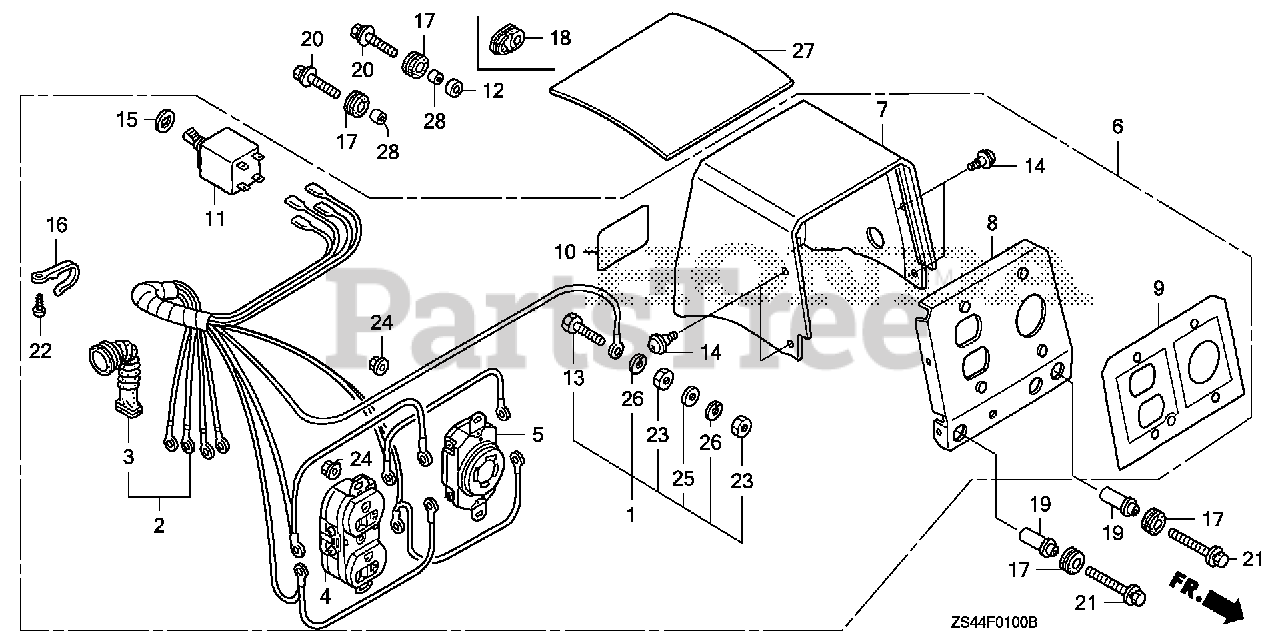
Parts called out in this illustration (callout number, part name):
1	TERMINAL SET, GROUND
2	WIRE HARNESS ASSY.
3	GROMMET, MAIN WIRE
4	RECEPTACLE (20A/125V) (EAGLE / RONG FENG)
5	RECEPTACLE (20A-125/250V)
6	BOX ASSY., CONTROL (NOT AVAILABLE)
7	COVER, CONTROL BOX
8	PANEL, FR.
9	MARK, PANEL SWITCH
10	MARK, PROTECTOR (ON-0FF)
11	PROTECTOR, CIRCUIT (13A)
12	COLLAR, CABLE CLAMP
13	BOLT, HEX. (6X22)
14	SCREW, SPECIAL (4X7.5)
15	WASHER, CROWN
16	TIE, CABLE
17	RUBBER, CONTROL BOX
19	COLLAR, CONTROL BOX
20	BOLT-WASHER (6X25)
21	BOLT-WASHER (6X45)
22	SCREW, TAPPING (4X16) (NOT AVAILABLE)
23	NUT, HEX. (6MM)
24	NUT, FLANGE (4MM)
25	WASHER, PLAIN (6MM)
26	WASHER, SPRING (6MM)
27	COVER, CONTROL BOX (LOWER)
28	COLLAR, CONTROL BOX
